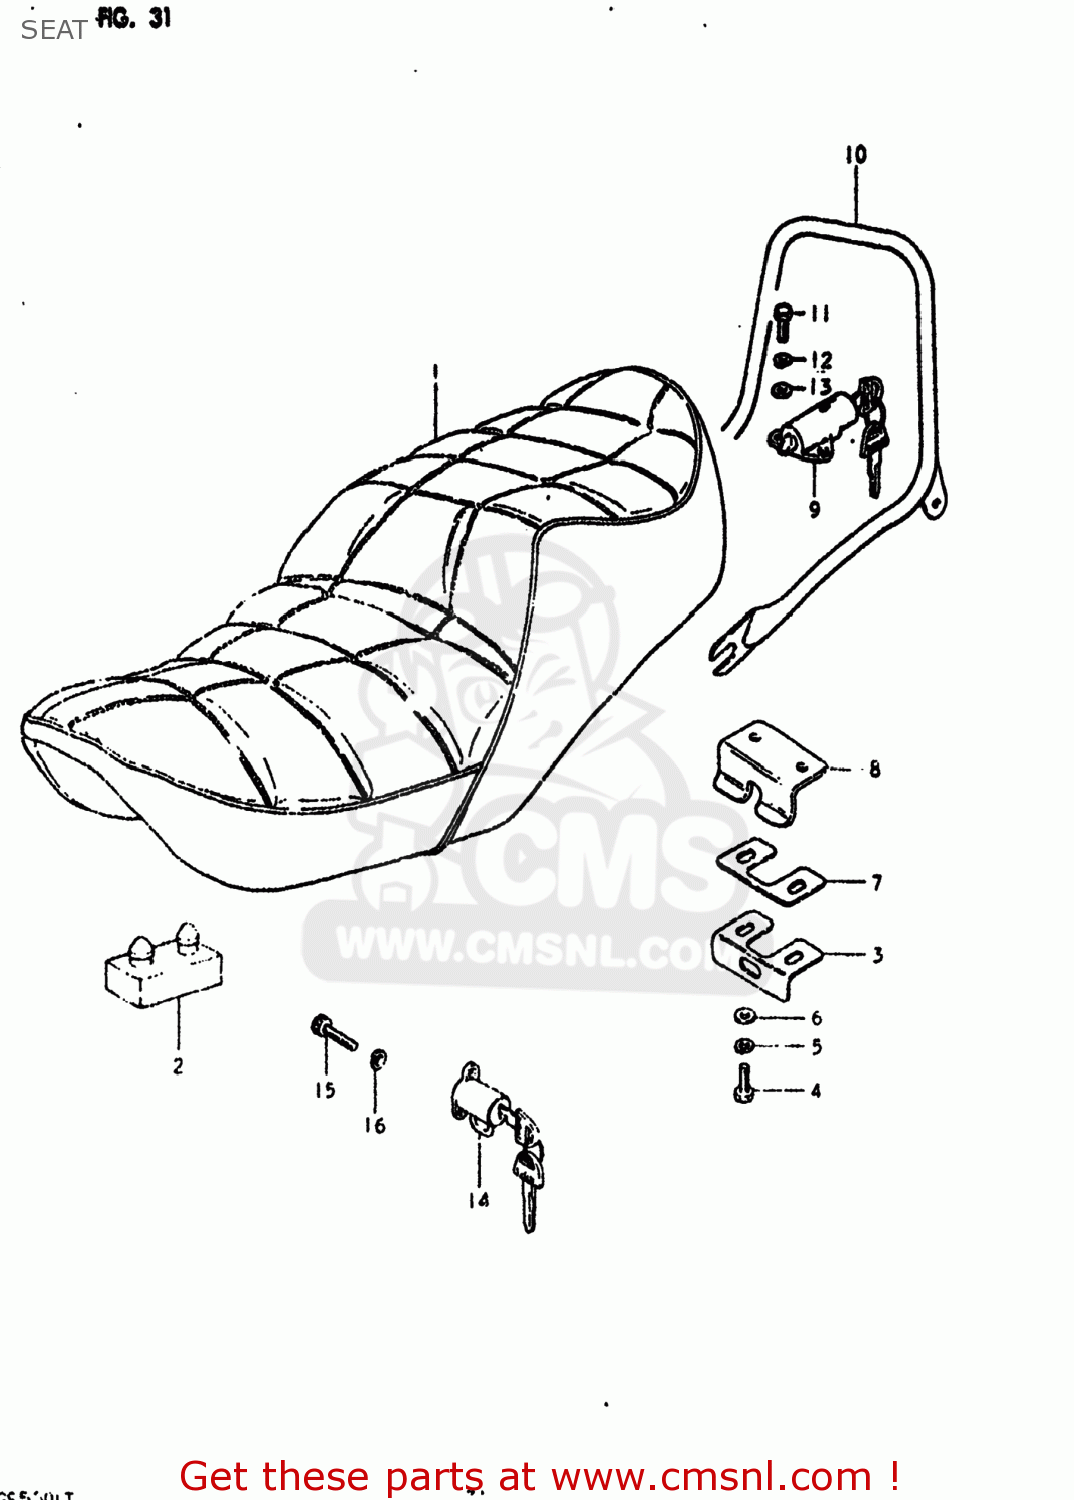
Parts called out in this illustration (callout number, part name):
1	SEAT ASSEMBLY
2	CUSHION
3	STRIKER,SEAT LOCK
4	BOLT, UPPER
5	LOCK WASHER
6	WASHER 6MM
7	SHIM,SEAT LOCK STRIKER
8	PLATE,SEAT LOCK
9	LOCK ASSEMBLY,SEAT
10	HANDLE,PILLION RIDER
11	BOLT
12	LOCK WASHER
13	WASHER 6MM
14	LOCK ASSEMBLY,HELMET
15	BOLT 6X11
16	LOCK WASHER
